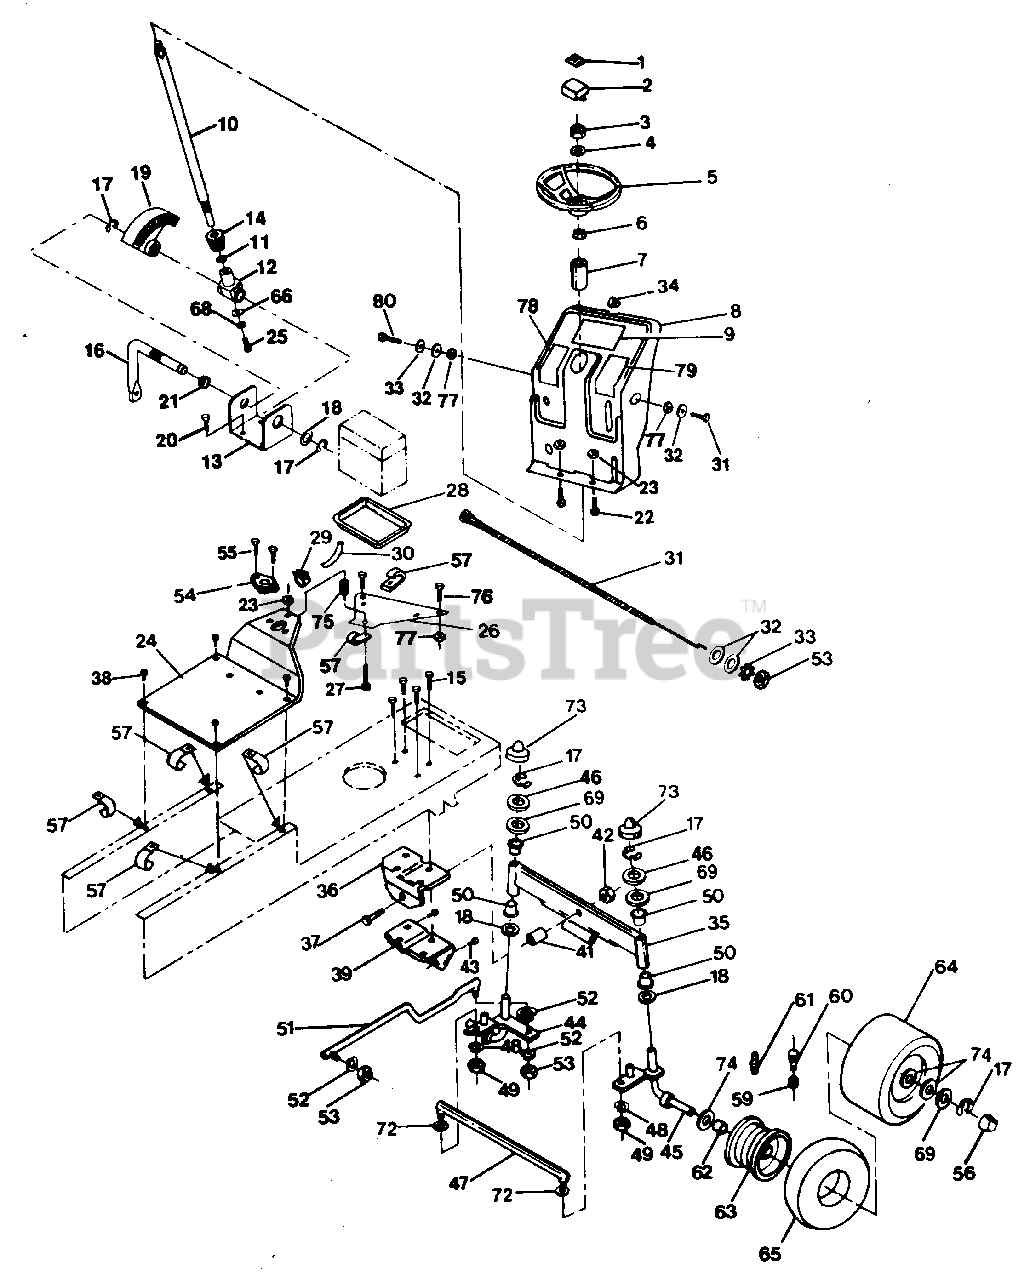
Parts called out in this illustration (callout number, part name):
1	Steering Wheel Cap Decal (AYP part number)
2	Steering Wheel Insert (AYP part number)
3	Hex Nut 1/2-20 (AYP part number)
4	Washer (AYP part number)
5	Steering Wheel (AYP part number)
6	Steering Wheel Adaptor (AYP part number)
7	Steering Sleeve (AYP part number)
8	Dash (AYP part number)
9	Dash Decal (AYP part number)
10	Steering Shaft (AYP part number)
11	Washer (AYP part number)
12	Shaft Support (AYP part number)
13	Steering Bracket (AYP part number)
14	Pinion Gear (AYP part number)
15	Special Screw (AYP part number)
16	Pitman Shaft (AYP part number)
17	Klip Ring (AYP part number)
18	Thrust Bearing (AYP part number)
19	Sector Gear (AYP part number)
20	Thread Rolling Hex Screw (AYP part number)
21	Snap-In Nyliner (AYP part number)
22	Truss Head Crown Screw (AYP part number)
23	Locknut (AYP part number)
24	Saddle (AYP part number)
25	Hex Screw (AYP part number)
26	Battery Plate Support (AYP part number)
27	Hex Bolt 5/16-18 x 2 (AYP part number)
28	Battery Tray (AYP part number)
29	Hose Clamp (AYP part number)
30	Tube (AYP part number)
31	Choke Control (AYP part number)
32	Washer 13/32 x 13/16 x 16 Ga. (AYP part number)
33	Ext. Tooth Lock Washer (AYP part number)
34	Dash Plug (AYP part number)
35	Front Axle (AYP part number)
36	Rear Saddle Support (AYP part number)
37	Hex Bolt (AYP part number)
38	Thread Roll Washer Hex Screw (AYP part number)
39	Front Saddle Support (AYP part number)
41	Front Bearing Axle Spacer (AYP part number)
42	Flange Locknut (AYP part number)
43	Thread Roll Washer Hex Screw (AYP part number)
44	L.H. Spindle (AYP part number)
45	R.H. Spindle (AYP part number)
46	Washer (AYP part number)
47	Tie Rod (AYP part number)
48	Lock Washer 5/16 (AYP part number)
49	Hex Nut 5/16-24 (AYP part number)
50	Bearing (AYP part number)
51	Drag Link (AYP part number)
52	Lock Washer 3/8 (AYP part number)
53	Hex Nut 3/8-24 (AYP part number)
54	Steering Bushing (AYP part number)
55	Hex Screw (AYP part number)
56	Front Hub Cap (AYP part number)
57	Fuel Line Clip (AYP part number)
59	Valve Cap (AYP part number)
60	Valve Stem (AYP part number)
61	Grease Fitting (AYP part number)
63	Front Rim 6" (AYP part number)
64	Front Tire (AYP part number)
65	Tube (Not furnished with Tractor)
66	Washer (AYP part number)
68	Lock Washer (AYP part number)
69	Washer (AYP part number)
72	Washer (AYP part number)
73	Spindle Cap (AYP part number)
74	Washer (AYP part number)
75	Spacer (AYP part number)
76	Hex Bolt (AYP part number)
77	Hex Nut (AYP part number)
78	Clutch Decal Attachment (AYP part number)
79	Lift Attachment Decal (AYP part number)
80	Hex Bolt (AYP part number)
